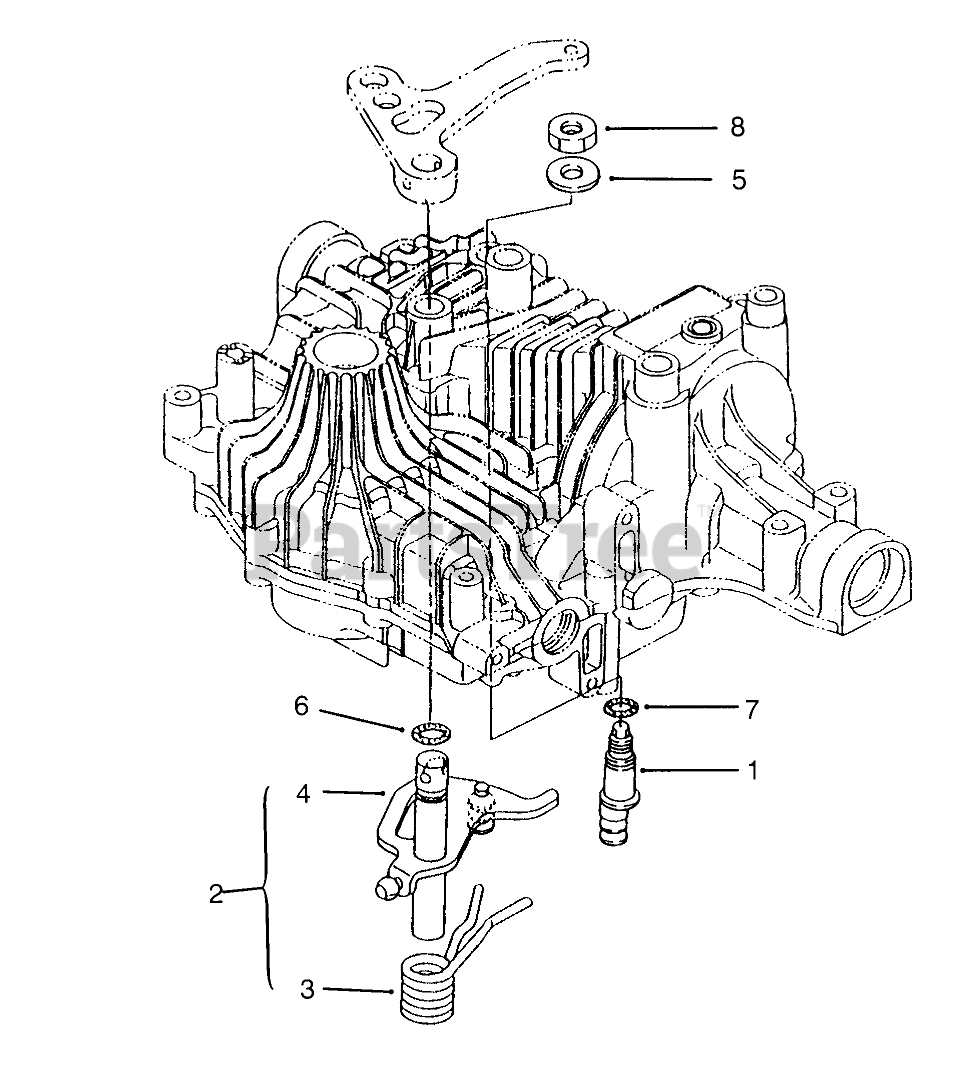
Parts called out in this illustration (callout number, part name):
1	Fulcrum (Only On: 72043,72063,72103)
2	Shaft ASM INCL 3-4 (Only On: 72043,72063,72103)
5	Washer (Only On: 72043,72063,72103)
6	Packing (Only On: 72043,72063,72103)
7	Packing (Only On: 72043,72063,72103)
8	Nut (Only On: 72043,72063,72103)
